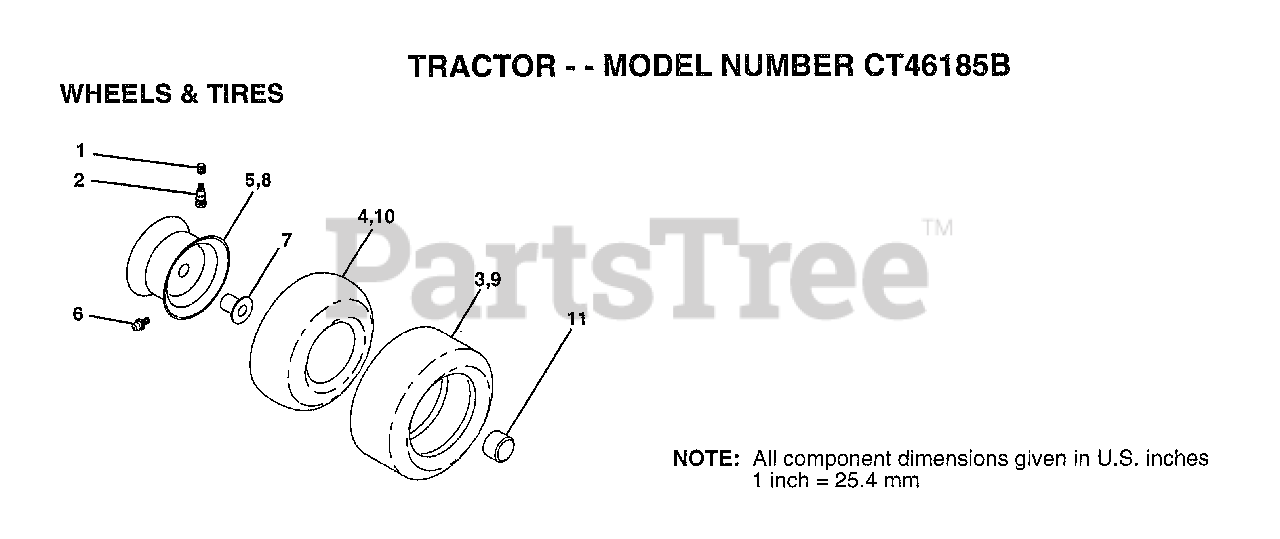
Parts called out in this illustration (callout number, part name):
1	VALVE CAP
2	VALVE STEM LT
4	TUBE.5.3/4.5/6
5	RIM ASSEMBLY, FRONT, 8"
6	FITTING LT
7	"FLANGE, BEARING"
8	RIM ASSEMBLY, REAR, 12"
10	TUBE.23X8/10-12
11	HUB CAP
